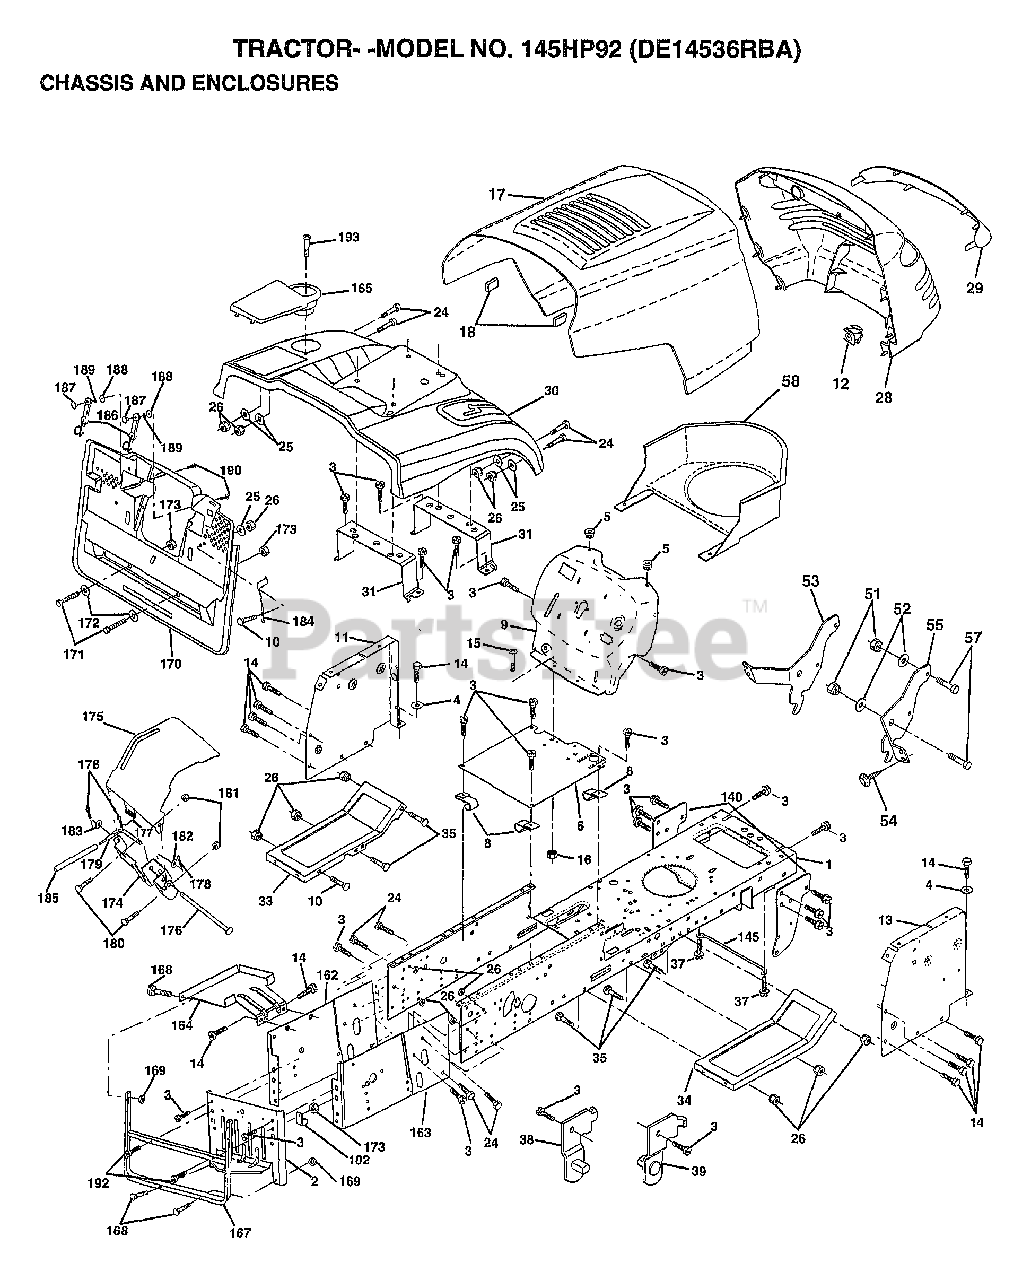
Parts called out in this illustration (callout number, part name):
1	CHASSIS.STAMPING
2	DRAWBAR.CRD
3	SCREW
4	WASHER
5	BUMPER-HOOD/DASH
6	SADDLE
8	"CLIP,INSULATOR"
9	DASH.SILKSCREEN
11	"PANEL-DASH,LH"
12	CLIP.TINNERMAN
14	SCREW LT
15	SCREW
20	"PLATE-MTG,BATT/FU"
24	BOLT
25	WASHER
26	NUT
28	GRILL
30	FENDER.CRD.SAGE
31	BRKT.SUPT.FENDER.CRD
33	FOOTREST
34	FOOTREST.PNT.RH
35	BOLT
37	SCREW LT
38	BRACKET ASM LH
39	BRACKET ASM RH
51	NUT
52	WASHER
53	BRACKET.GRILLE.LH
54	SCREW.HEX.WS.HD
55	BRACKET.GRILLE.RH
58	AIR DUCT
102	CLIP T
125	SCREW
140	BRKT SUSPENSION
145	"ROD POVOT,CHASSIS"
162	BRKT.EXT.CHASSIS.LH.CRD
163	BRKT.EXT.CHASSIS.RH.CRD
164	SUPPORT.BATTERY.CRD
165	COVER.BATTERY.CRD.BLACK.LT
167	SUPT.ASM.BACKPLATE
168	BOLT-RD HD SQ NK
170	COVER.BACKPLATE.BLACK
171	BOLT.HEX.3/8-16X2-1/2
173	NUT
174	BRKT.SWITCH.FBI.CRD
175	GRUARD.DOOR.REAR.CRD
176	HINGE PIN
177	SPRING.COVER.LH
179	ROD.PIVOT.FBI.CRD
182	WASHER.385X.625
183	WASHER
184	BRKT.ACTUATOR.BAG.CRD
185	TUBE.LEVER.SWCH.FBI.CRD
186	LATCH ASSY.BAGGER
187	WELDNUT
188	WASHER #10
189	LOCKWASHER
190	SCREW
192	SCREW LT
193	SCREW LT
